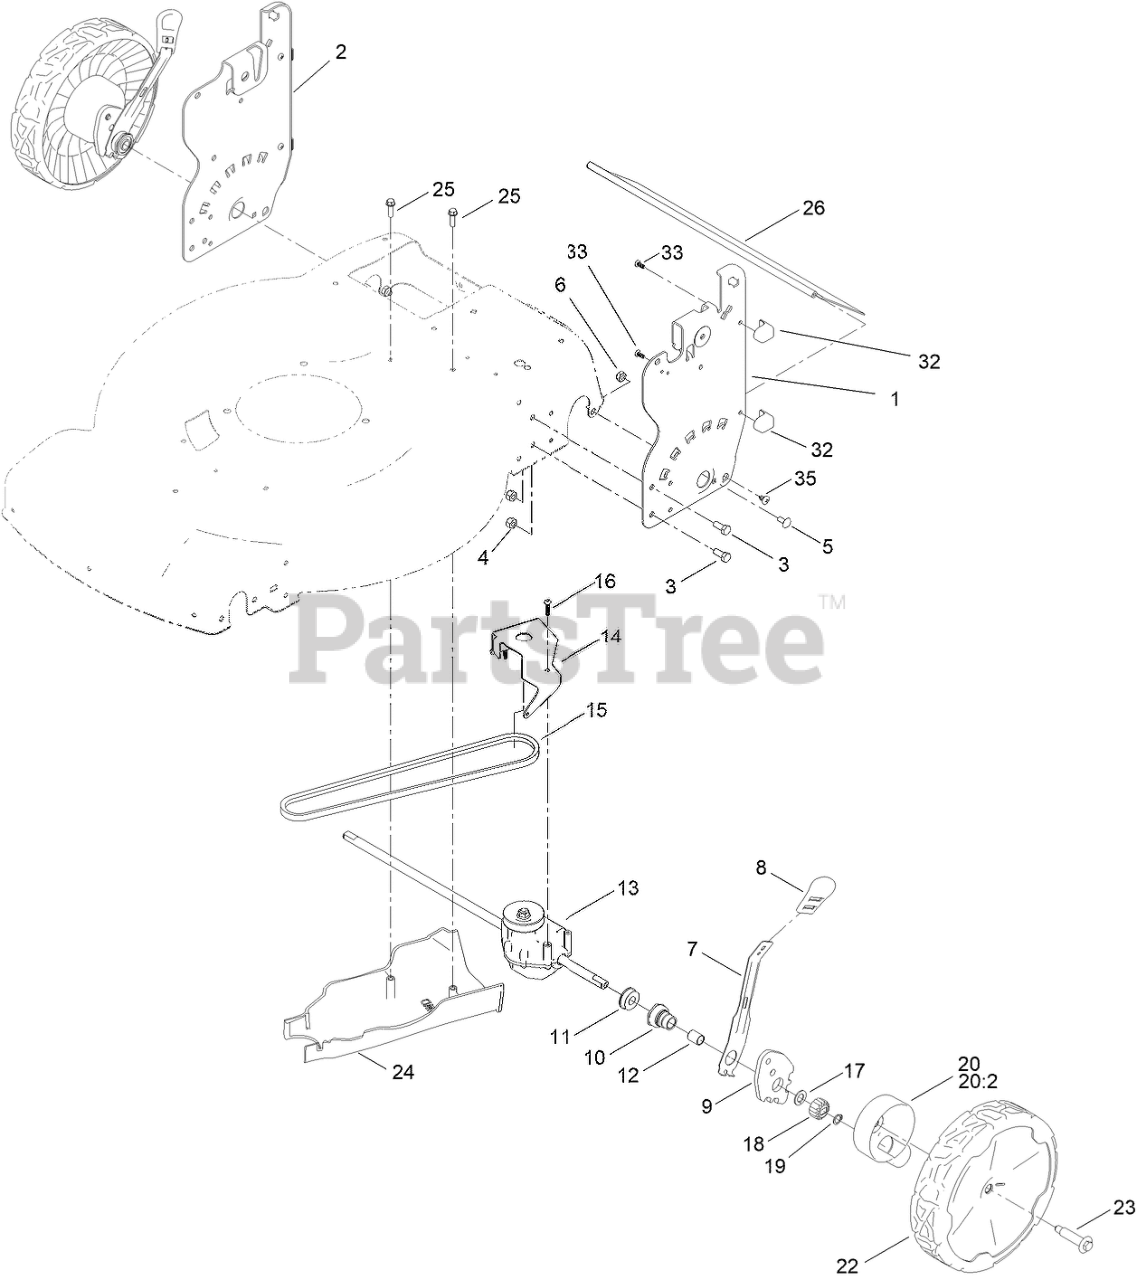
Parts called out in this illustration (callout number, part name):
1	PLATE-HOC, LH
2	PLATE-HOC, RH (2 HOLE)
3	SCREW-HH
4	NUT-LOCK, NI
5	SCREW-CARR
6	NUT-LOCK, NI
7	ARM-SPRING
8	KNOB-HOC
9	ARM-PIVOT, REAR
10	RETAINER-BUSHING, HOC
11	BEARING-BALL
12	BUSHING-SLEEVE
13	TRANSMISSION-RWD
14	BRACKET-TRANSMISSION
15	V-BELT
16	SCREW-PLASTITE
17	WASHER-THRUST
18	GEAR-PINION, 15T
19	RING-RETAINING
20	ASM-COVER, GEAR (DK GRAY)
20:2	WASHER-STEPPED
22	ASM-9.65" WHEEL, GEARED
23	WHEEL BOLT
24	COVER-BELT, RWD
25	SCREW-HWH
26	SHIELD-TRAILING
32	PAD-SMART STOW
33	SCREW-PLASTITE
35	SCREW-PTH
